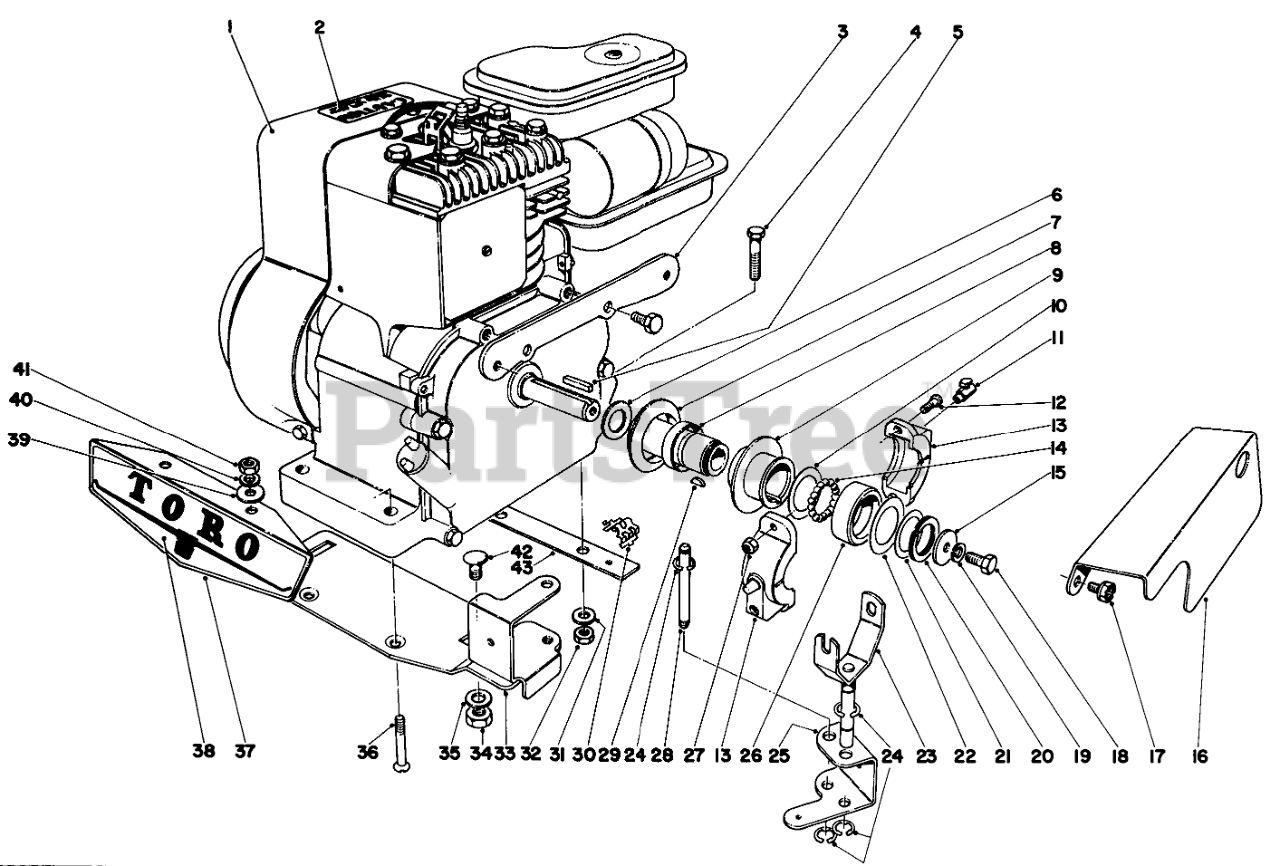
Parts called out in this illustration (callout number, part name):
1	Engine
2	Decal
3	Bracket
4	Screw
5	KEY-SQUARE
6	Washer
7	CLUTCH BODY ASM
8	IDLER BUSHING
9	SLIDING FLANGE
10	Thrust Washer
11	OIL CUP (OBS)
12	SCREW
13	Slip Ring
14	BALL-STEEL
15	Washer
16	Belt Guard
17	Screw
18	SCREW-HH
19	WASHER-LOCK
20	Snap Ring
21	WASHER
22	WASHER
23	SHIFT FORK ASM
24	RING-RETAINING, EXT
25	Bracket Shift Fork
26	Shift Collar
27	NUT-LOCK
28	Pivot Shaft
29	KEY-WOODRUFF
31	WASHER-PLAIN
32	NUT-LOCK NI
33	Clutch Mounting Plate
34	Nut
35	WASHER-PLAIN
36	Screw
37	Name Plate
38	Decal
39	WASHER-FLAT
40	WASHER-LOCK
41	NUT-HEX
42	BOLT-CARR
